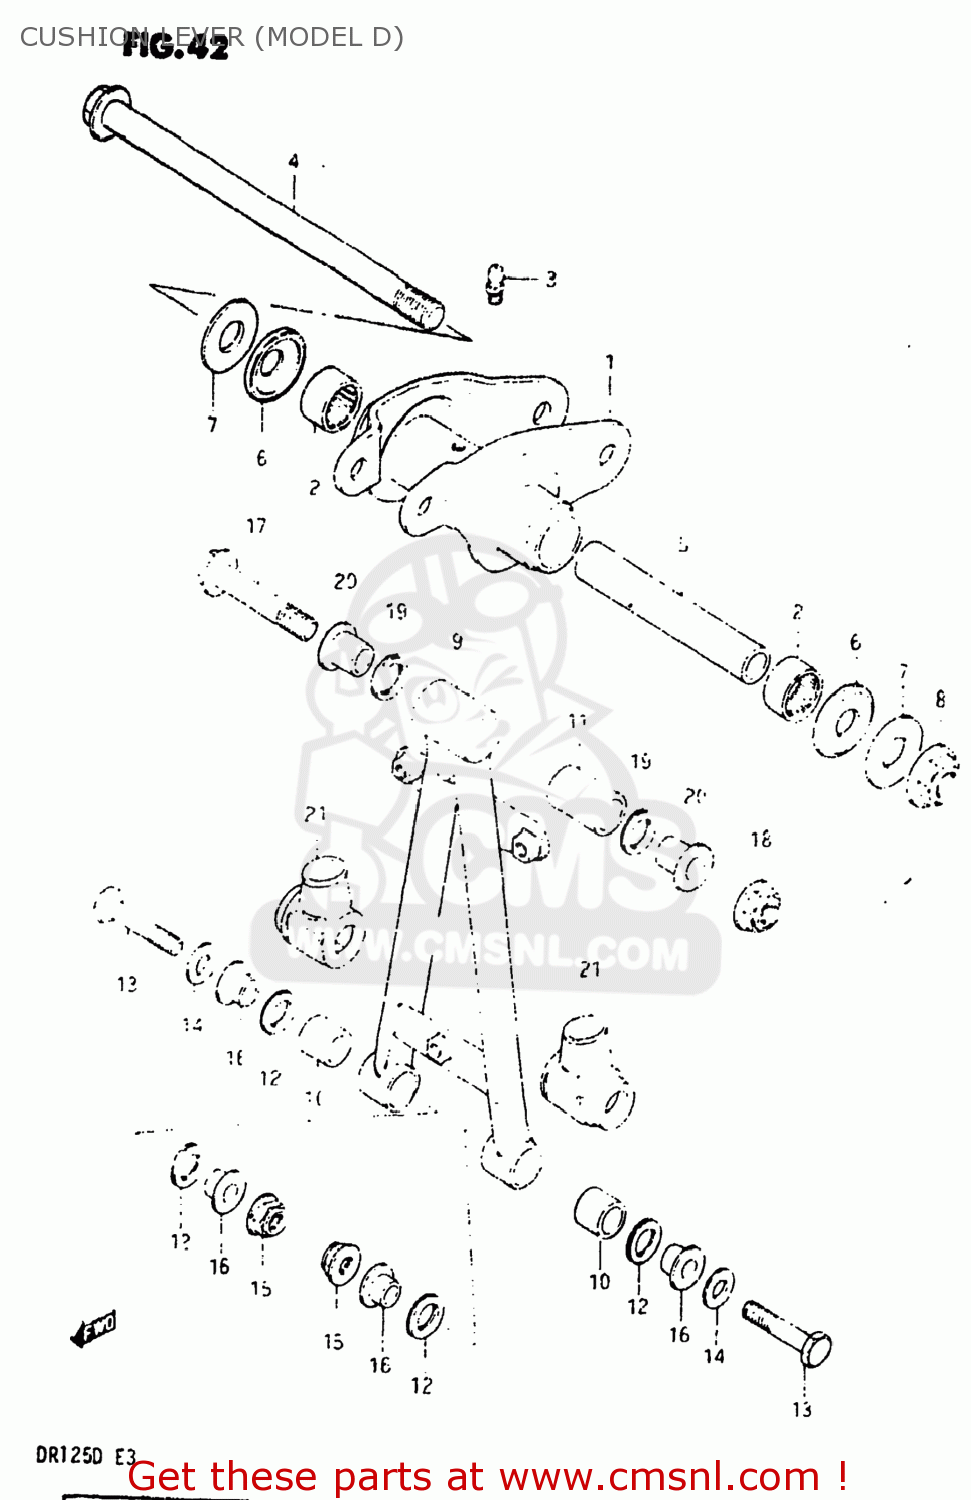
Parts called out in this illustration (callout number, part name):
1	LEVER ASSEMBLY,REAR CUSHION
2	BEARING(17X25X20)
3	GREASE NIPPLE
4	SHAFT,REAR CUSHION LEVER
5	SPACER,REAR CUSHION LEVER
6	DUST SEAL,REAR CUSHION,LEFT
7	WASHER
8	NUT 12MM
9	ROD SET,REAR CUSHION LEVER
10	BUSHING
11	BUSH,UPPER
12	DUST SEAL,RR CUSHION LOD LWR
13	BOLT,REAR CUSHION ROD
14	WASHER
15	NUT
16	SPACER,RR CUSHION ROD LWR
17	BOLT(10X65)
18	NUT
19	DUST SEAL,LEVER CUSHION UNIT
20	SPACER,RR CUSHION ROD UPR
21	BOOT,REAR CUSHION ROD,LOWER
